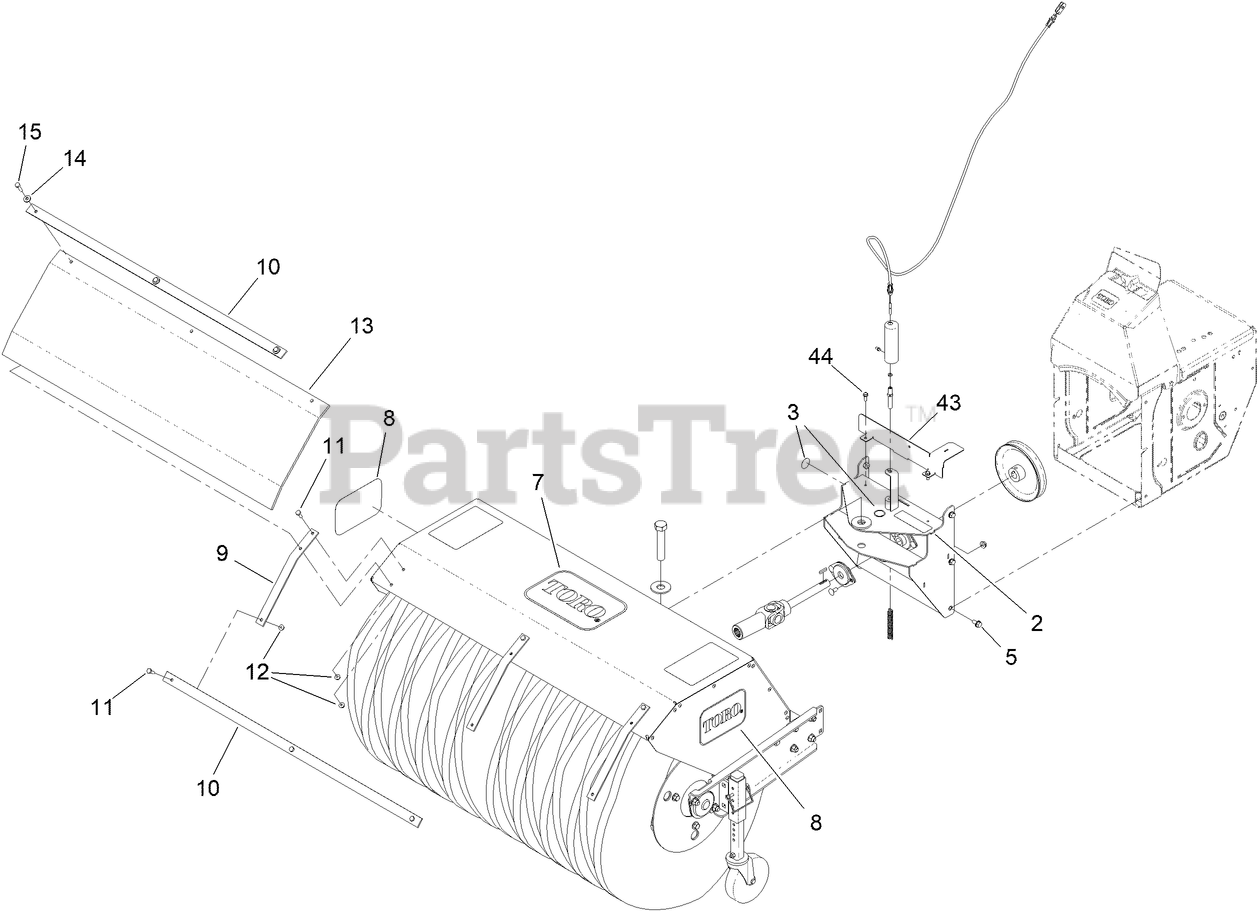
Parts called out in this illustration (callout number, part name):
2	DECAL-COVER, MISSING
3	DECAL-GREASE
5	SCREW-HWHTF
7	DECAL
8	DECAL-Z-LOGO
8	DECAL
9	STRAP-SUPPORT, DEFLECTOR
10	STRAP-SUPPORT, BROOM DEFLECTOR
11	SCREW-HH
12	NUT-HF
13	DEFLECTOR-BROOM
14	WASHER-FLAT
15	SCREW-HHF
43	PLATE-COVER
44	SCREW-HWH
